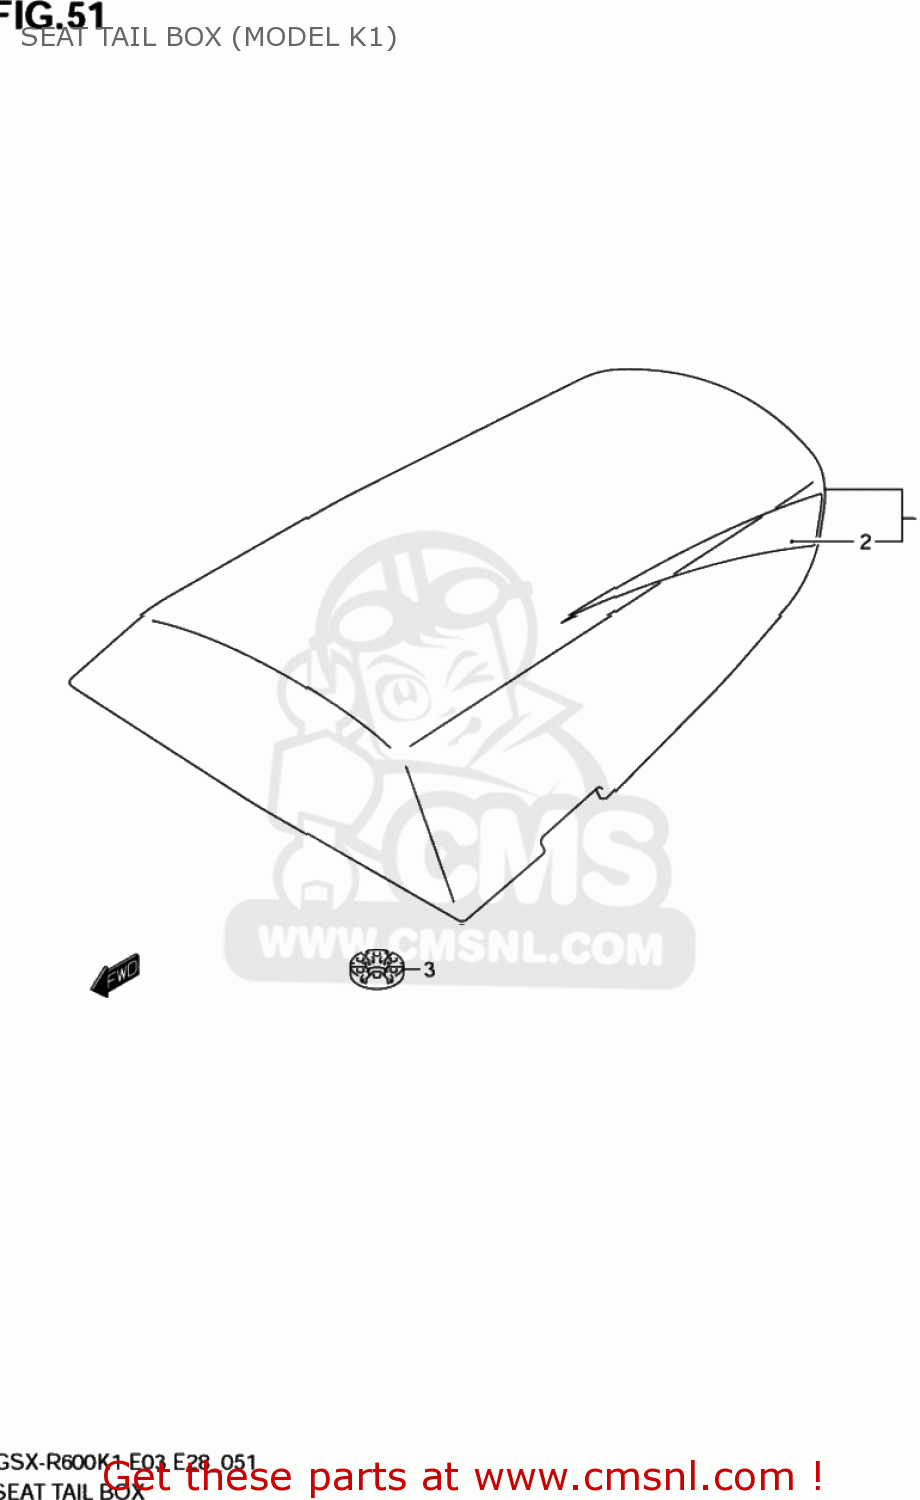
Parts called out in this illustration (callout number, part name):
1	BOX ASSY,SEAT
2	TAPE SET,BOX SEAT TAIL(BLACK)
3	CUSHION
